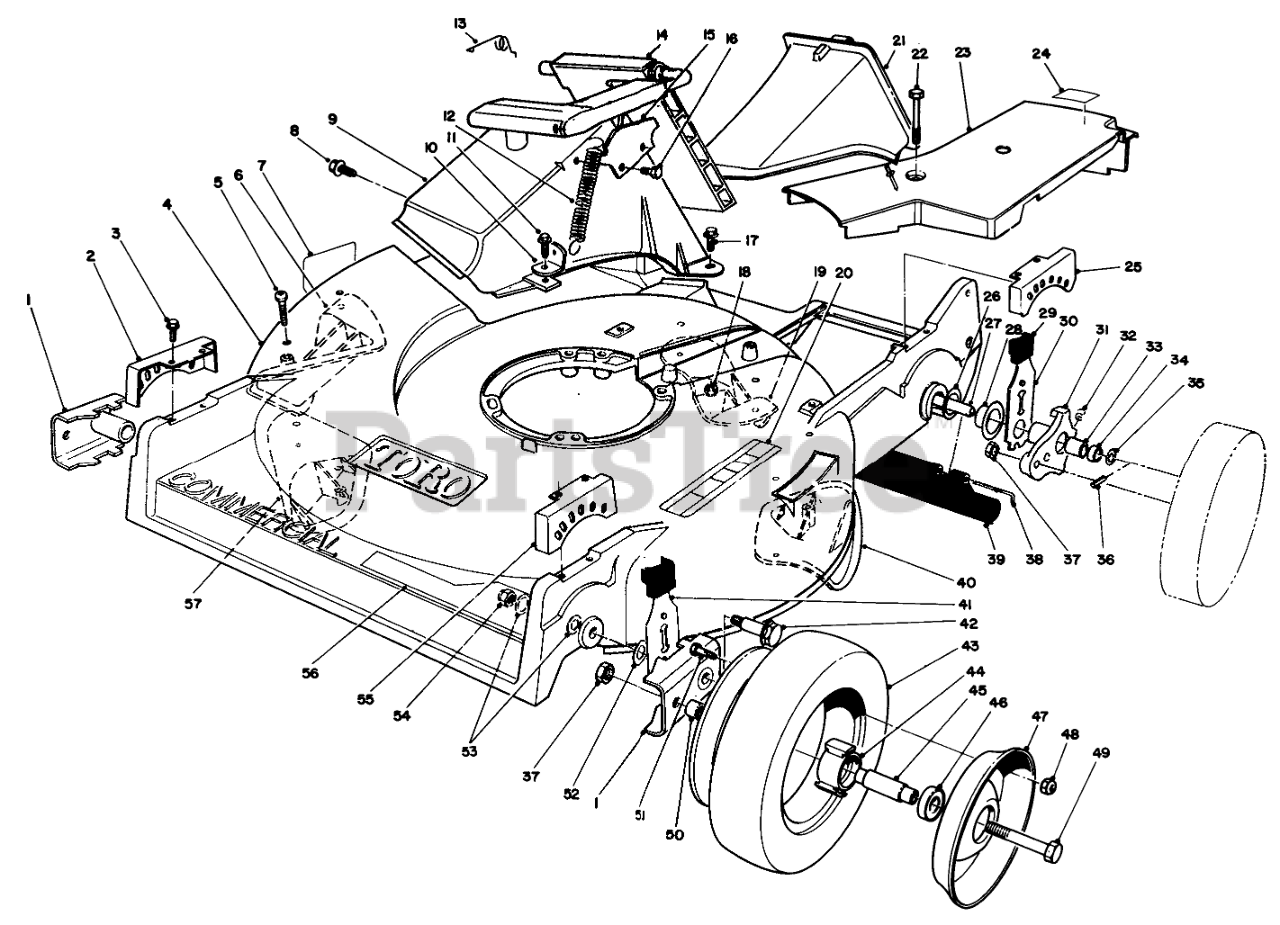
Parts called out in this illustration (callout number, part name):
1	ARM-PIVOT, FRONT
2	QUADRANT-FRONT, RH
3	SCREW-HWHTF
4	Housing (Incl. Ref. #7 & 27)
5	SCREW-PPH
6	KICKER
7	DECAL-DANGER
8	SCREW AND WASHER ASM
9	DISCHARGE TUNNEL
10	Bracket-Spring
11	SCREW-HWHTF
12	SPRING-DOOR
13	RETAINER-DOOR
14	DOOR ASSEMBLY
15	DOOR LATCH PLATE
16	SCREW-PLASTITE
17	SCREW-HH
18	NUT-LOCK, NI
19	KICKER
20	DECAL-INSTRUCTION, SAFETY
21	DISCHARGE PLUG ASM
22	SCREW-HHFTF
23	COVER-BELT
24	LABEL-GREASE, HP
25	QUADRANT-REAR, LH
26	WASHER
27	SHAFT-AXLE, REAR
28	CAP-END
29	KNOB-ARM
30	REAR SPRING ARM ASM
31	Arm-Pivot (Incl. Ref. #32-34)
32	FITTING-GREASE
33	BUSHING
34	BUSHING
35	WASHER-PLAIN
36	PIN-SPIROL
37	NUT-LOCK, CONE
38	ROD-SHIELD
39	SHIELD-TRAILING
40	KICKER
41	FRONT SPRING ARM ASM
42	WHEEL BOLT
44	HUB-BEARING
45	SPACER-BEARING
46	BEARING-WHEEL
47	Wheel-Half
48	NUT-LOCK, NI
49	SCREW-HH
50	SPACER-WHEEL
51	SCREW-HH
52	WASHER-THRUST
53	WASHER
54	Nut
55	QUADRANT-FRONT, LH
56	DECAL - RECYCLER
57	KICKER
